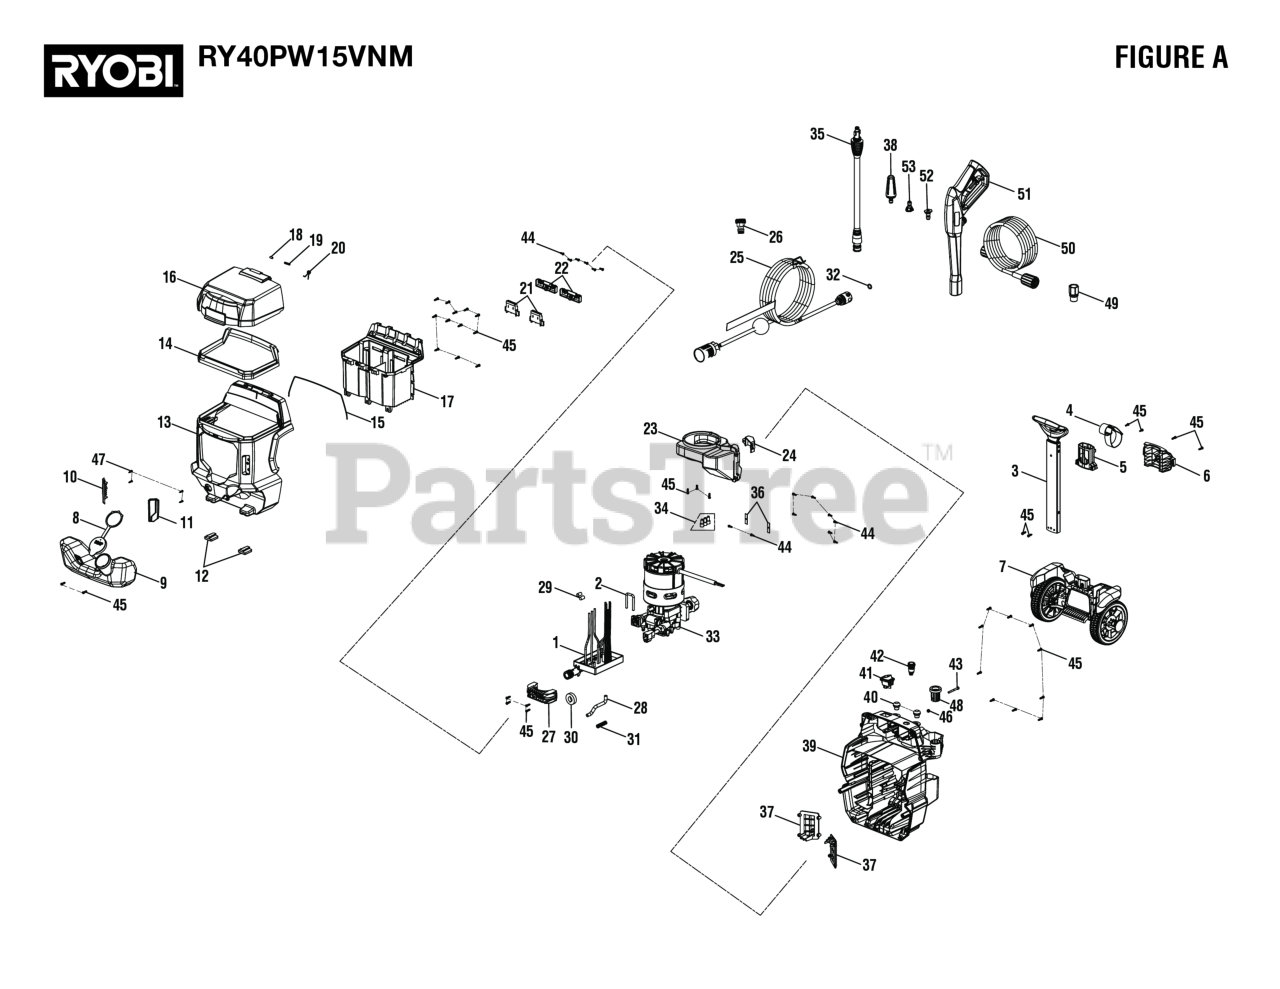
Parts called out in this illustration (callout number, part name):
1	36V DC Controller
2	"U" Clip (3.0 Dia.)
3	Retractable Handle Assembly
4	Hook and Loop Strap
5	Hose Bracket
6	Holder Cover
7	Wheel Base Assembly (See Fig C)
8	Detergent Tank Cap
9	Soap Tank
10	Mount Cover (Left)
11	Mount Cover (Right)
12	Rubber Foot
13	Front Housing
14	Battery Cover Rubber Seal
15	Front Housing Rubber Seal
16	Battery Cover
17	Battery Tray
18	Battery Door Axle
19	Compression Spring
20	Battery Cover Spring
21	Battery Holder Assembly (See Fig B)
22	Battery Cover Connector
23	Motor Ventilation
24	Motor Air Cover
25	Suction Hose w/Swivel Connector
26	Inlet Connector
27	Pump Bracket
28	Siphon Tube
29	Shock Absorbing Bushing
30	Outlet Tube Cover Foam
31	Detergent Tank Spring (Compression Spring
32	O-Ring (ID11.3 x CS2.5)
33	Motor and Pump Assembly
34	Close-End Connector
35	Spray Wand Assembly
36	Metal Plate
37	Corner Cover
38	Turbo Nozzle
39	Rear Housing
40	Nozzle Grommet
41	Power Switch
42	Boost Button
43	Bolt (M5 x 42 mm)
44	Screw (ST3.5 x 15 mm, Pan Hd.)
45	Screw (M4.2 x 15 mm, Phillips Hd. S.T.)
46	Lock Nut (M5 x 0.8 mm)
47	Screw (M2.9 x 14 mm, Pan Hd.)
48	Primer Post Rubber Seal
49	Priming In-Line Accessory
50	25 ft. Hose
51	Trigger Handle
52	15 Deg Nozzle
53	Soap Nozzle (Blue)
